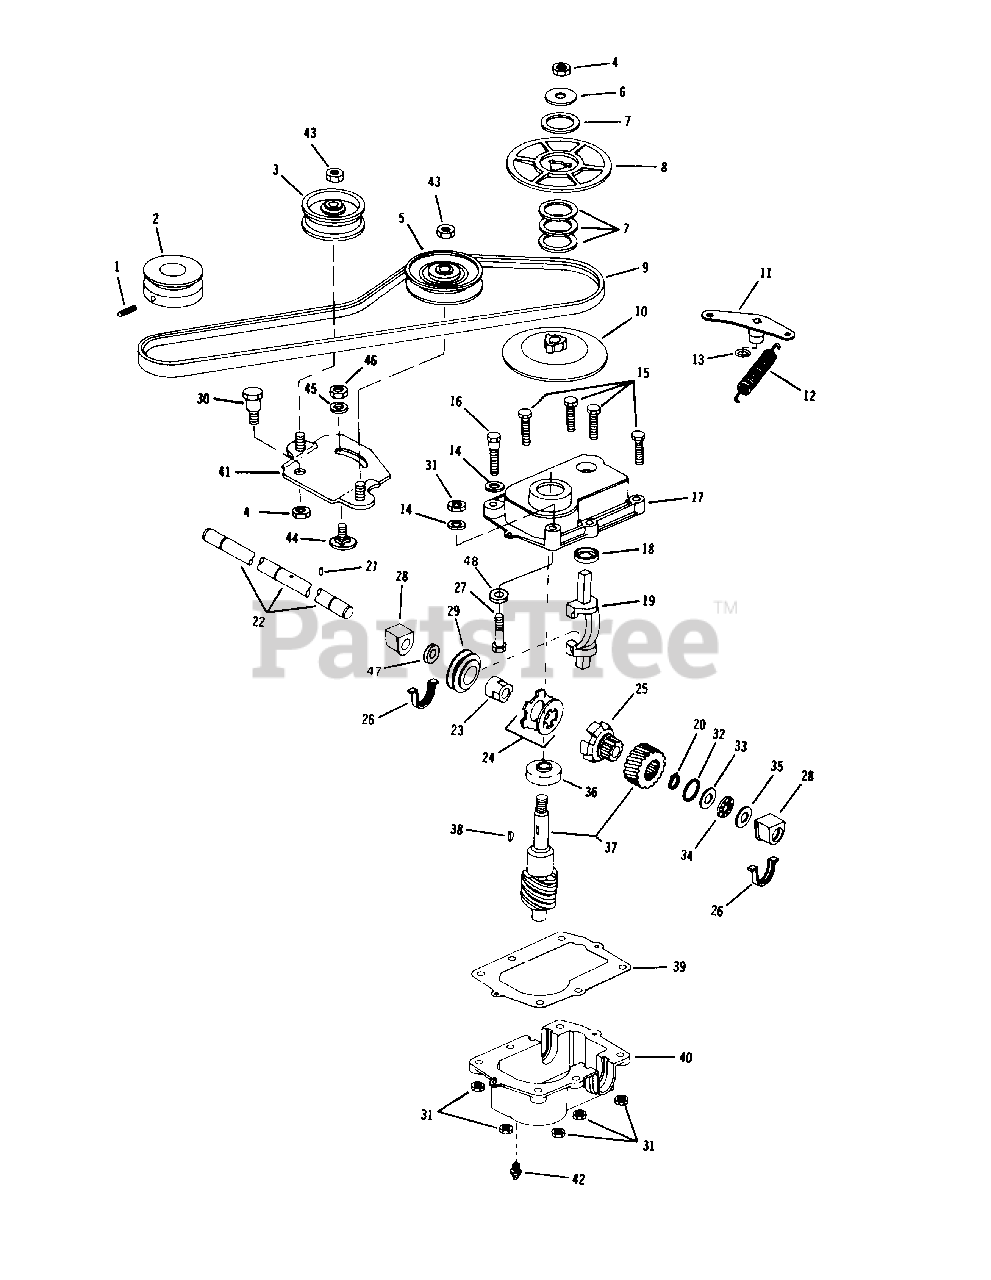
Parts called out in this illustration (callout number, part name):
1	Set Screw
2	Pulley-Engine
3	Pulley-Idler Variable Speed
4	Nut
5	Idler-V-Belt
6	Washer
7	Washer
8	Pulley Half-Upper
9	V-Belt
10	Pulley Half-Lower
11	Shift Arm
12	Spring-Extension
13	O-Ring
14	Washer
15	Screw-Hex Head Cap
16	Bolt-Shoulder
17	Gear Case-Upper
18	Seal Guide
19	Fork-Shift
20	Ring-Retaining
21	Pin
22	Driveshaft
23	Driven Sleeve
24	Disc Clutch Kit
25	Driver
26	Packing
27	Screw
28	Bearing & Seal Asy.-Gearcase
29	Collar
30	Bolt-Shoulder
31	Nut
32	Washer-Thrust
33	Washer-Thrust
34	Bearing-Thrust
35	Washer-Thrust
36	Bearing
37	Worm Wheel and Shaft Assembly
38	Key
39	Gasket
40	Gear Case-Lower
41	Idler Plate
42	Lubrication Fitting
43	Nut-Thin
44	Bolt-Square Neck
45	Washer
46	Nut
47	Washer
48	Lockwasher
